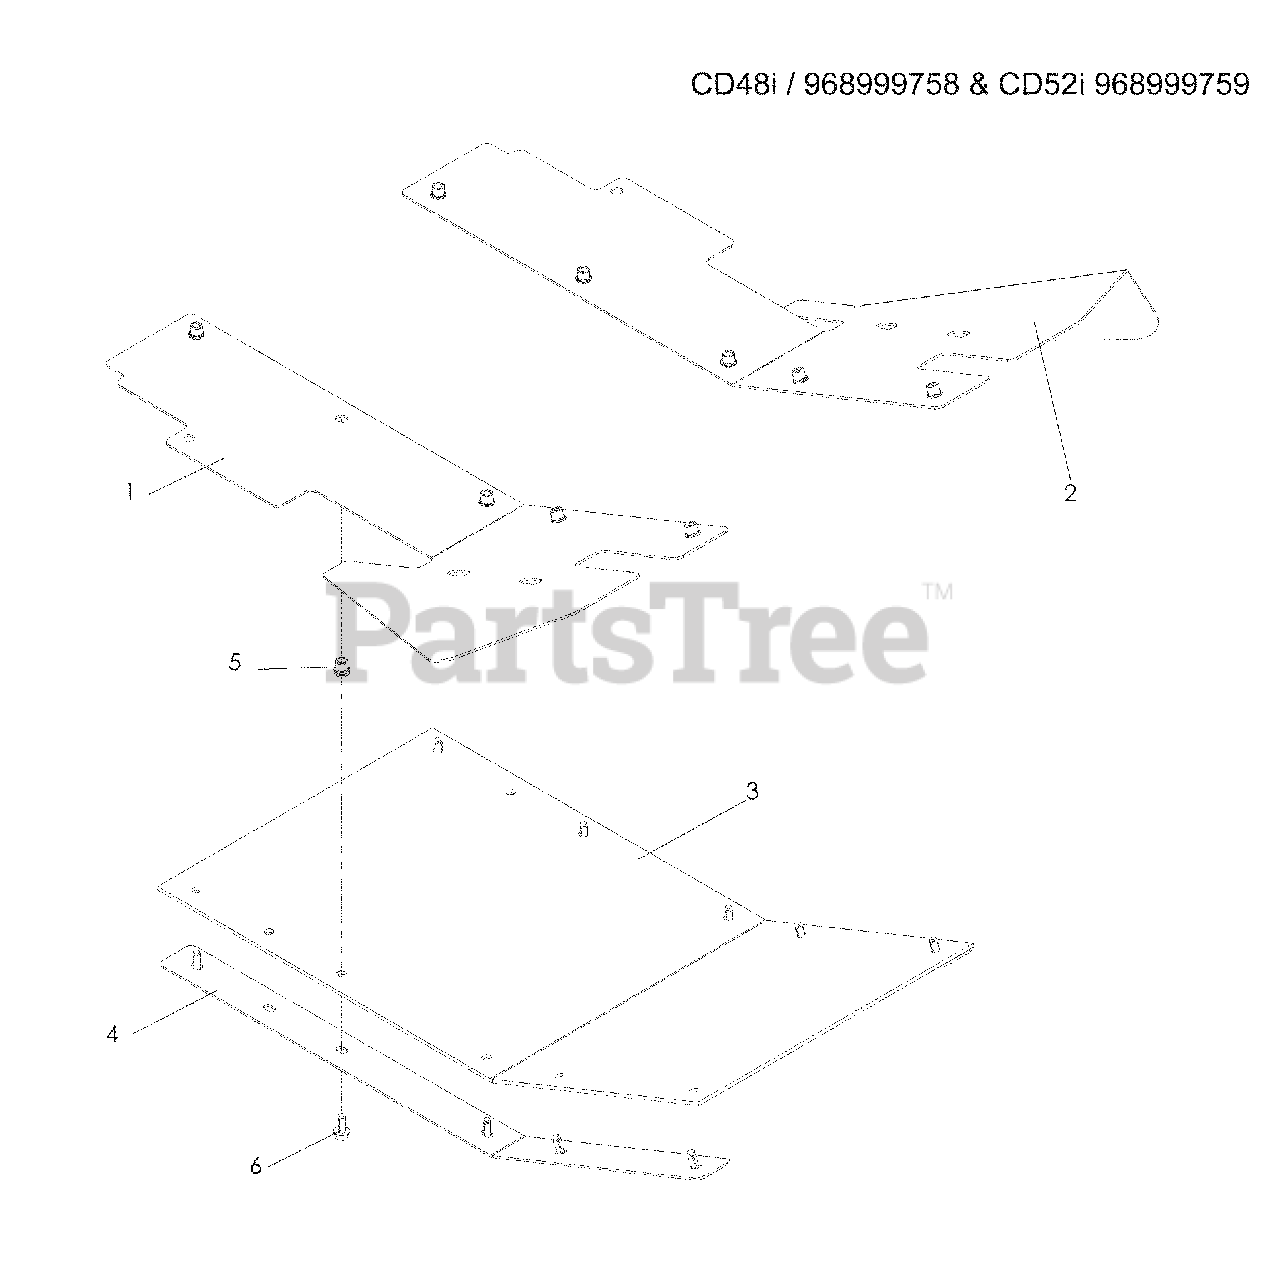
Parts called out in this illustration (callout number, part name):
1	GUARD, DEBRIS, RIGHT
2	GUARD, DEBRIS, LEFT
3	GUARD, RUBBER
4	STRAP, GUARD
5	KNURLED INSERT, ¼-20
6	SCREW, ¼-20 x 5/ THDROLL
